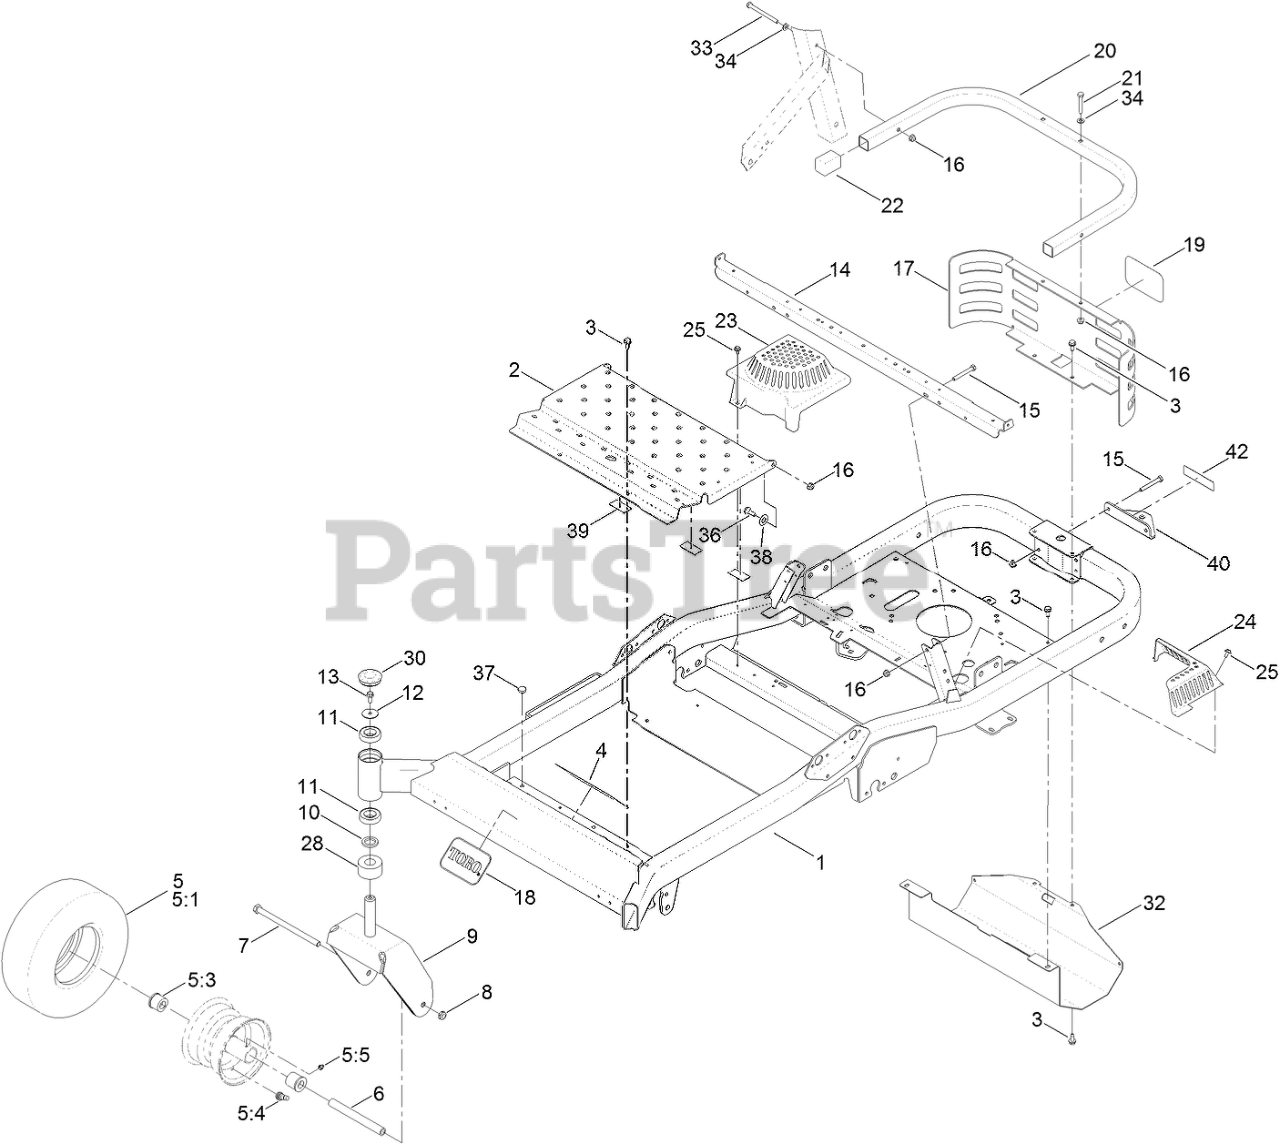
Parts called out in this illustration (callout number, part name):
1	FRAME ASM
2	PAN-FLOOR
3	SCREW-HWHTF
4	DECAL-DANGER
5	TIRE AND WHEEL ASM
5:1	TIRE-13 INCH SMOOTH
5:3	BUSHING-FLANGE
5:4	STEM-VALVE
5:5	FITTING-GREASE
6	SPANNER
7	SCREW-HH
8	NUT-LOCK, NI
9	FORK-CASTER
10	WASHER-THRUST
11	BEARING-BALL
12	WASHER-FLAT
13	SCREW-HHF
14	SUPPORT-SEAT
15	SCREW-HH
16	NUT-HF, NI
17	GUARD-REAR
18	DECAL
20	TUBE-GUARD
21	SCREW-HH
23	COVER-FAN, RH
24	COVER-FAN, LH
25	SCREW-HHFTF
28	SPACER-CASTER
30	CAP-GREASE
32	SHIELD-HEAT
33	SCREW-HH
34	WASHER-PLAIN
36	SCREW-SHOULDER
37	BUMPER
38	WASHER-TEFLON
39	PAD-RUBBER
40	BRACKET-HITCH
